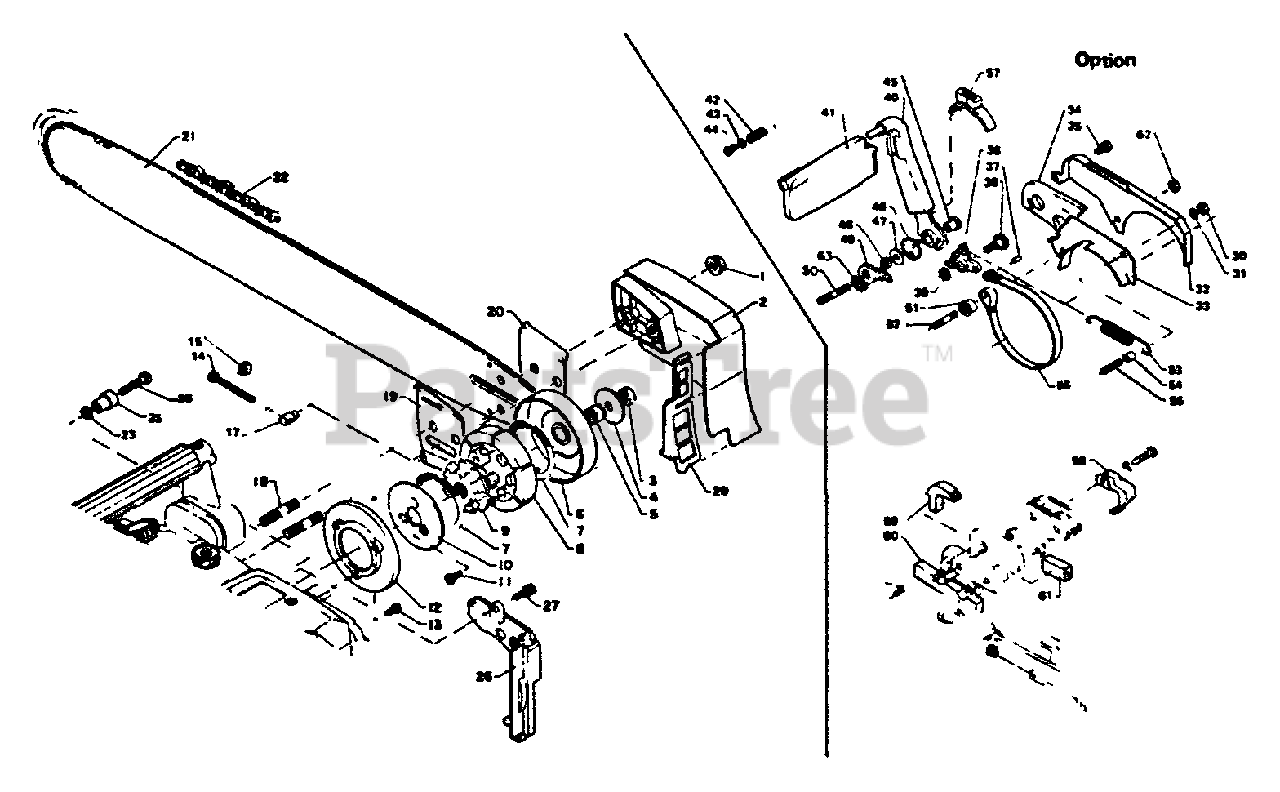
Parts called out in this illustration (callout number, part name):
1	NUT - FLANGE
2	GUARD, SPROCKET
3	LOCKNUT
4	WASHER, CLUTCH
5	BEARING, NEEDLE
6	DRUM, CLUTCH
7	SPRING, CLUTCH
8	SHOE, CLUTCH
9	HUB, CLUTCH
10	PLATE, CLUTCH
11	SCREW - 5X12
12	SEAL, DUST
13	SCREW - 4X10
14	SCREW, TENSIONER
17	TENSIONER, CHAIN
18	STUD, GUIDE BAR
19	PLATE, GUIDE - INNER
20	PLATE, GUIDE - OUTER
21	GUIDE BAR
22	Chain
23	WASHER - 5
25	CATCHER, CHAIN
26	ADAPTOR
27	SCREW - 5X14
28	SCREW - 5X25
29	PAD
30	NUT - 5
31	LOCKWASHER - 5
32	COVER, BRAKE
33	COVER, BRAKE - INNER
34	SEAL
35	SCREW - 5X8
36	LEVER, BRAKE
37	PIN - SPRING -- 4X8
38	BOLT
39	WASHER - 6
39	BRAKE LEVER ASSY
40	HANDLE, BRAKE
41	HANDLE, BRAKE - B
42	SPRING
43	WASHER - 4
44	SCREW - 4X10
45	NUT
46	SPRING, RETURN
47	WASHER
48	SPACER
49	CONNECTOR
50	STUD
51	ADJUSTER, BRAKE BAND
52	STUD
53	SPRING
54	COLLAR
55	STUD
56	BAND, BRAKE
57	COVER, BRAKE
58	SEAL
59	SEAL
60	SEAL
61	SEAL
62	LOCKNUT - 5
63	STOPPER
